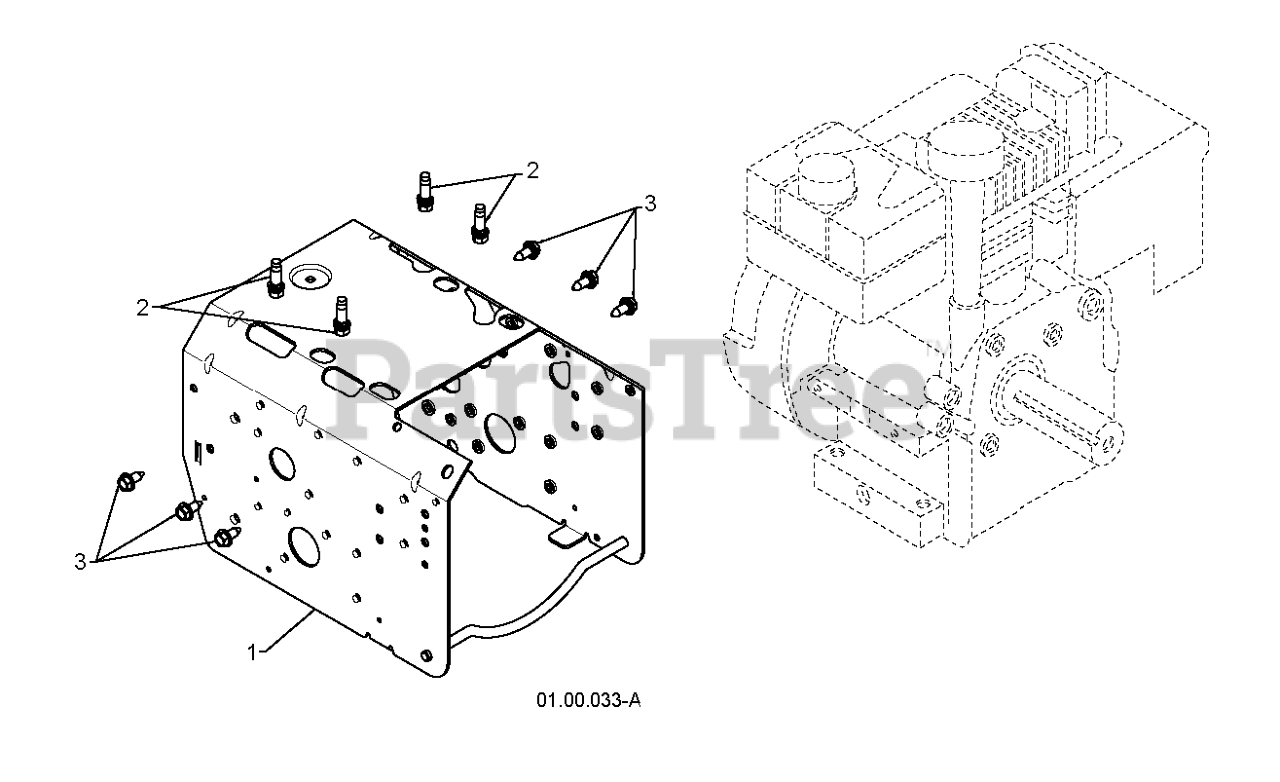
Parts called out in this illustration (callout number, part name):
1	FRAME.WELD.PNT.GEAR.ORANGE
2	BOLT 3/8-16X1-1/8
3	BOLT.HEX.HD.WASHER.5/16-18X.75
